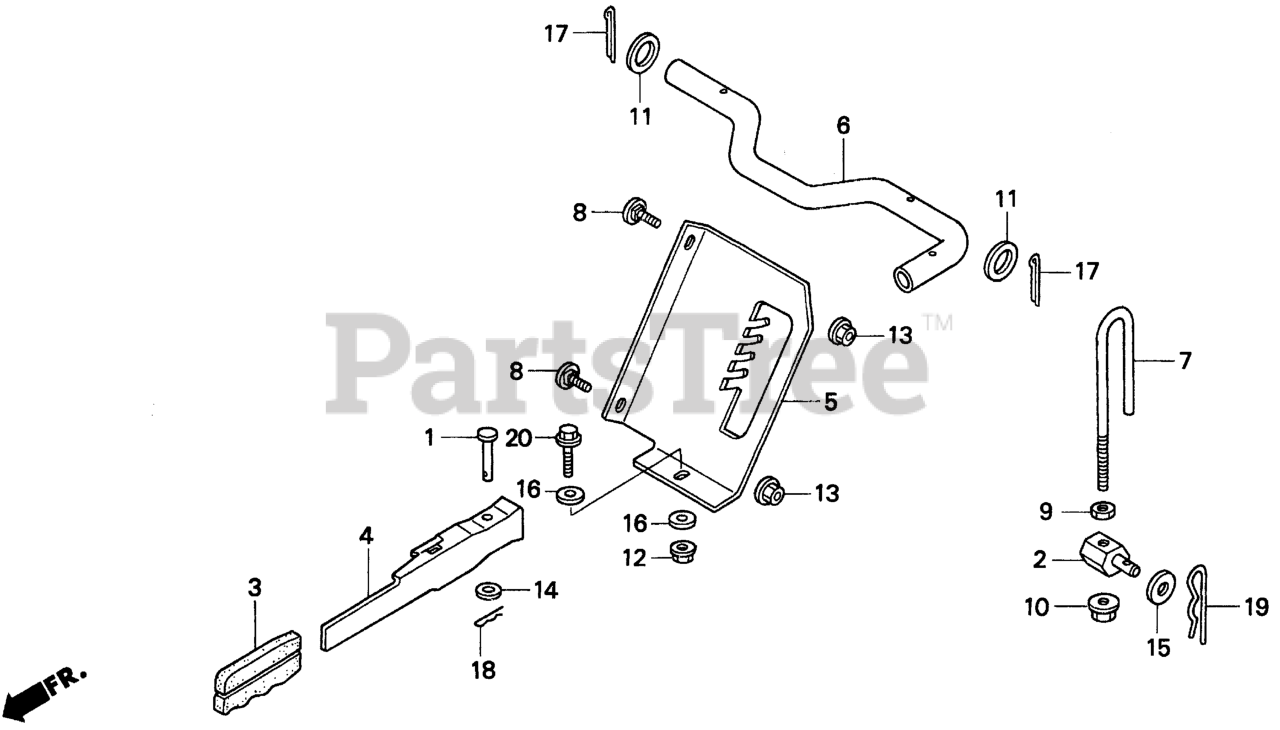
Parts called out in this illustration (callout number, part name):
1	PIN, STEP BAR JOINT
2	PIN, RR. LINK ADJUSTING
3	GRIP, HEIGHT ADJUSTMENT
4	LEVER, HEIGHT ADJUSTMENT
5	PLATE, RATCHET
7	BAR, ADJUSTMENT
8	BOLT, SPECIAL (9X15)
9	NUT, LOCK (12MM)
10	NUT, SELF-LOCK (OHASHI)
11	WASHER, PLAIN (26MM)
12	NUT, FLANGE (6MM)
13	NUT, FLANGE (8MM)
14	WASHER, PLAIN (8MM)
15	WASHER, PLAIN (14MM)
16	WASHER, PLAIN (6MM)
17	PIN, COTTER (5.0X40)
18	PIN, LOCK (8MM)
19	PIN, LOCK (14MM)
20	BOLT, FLANGE (6X35)
